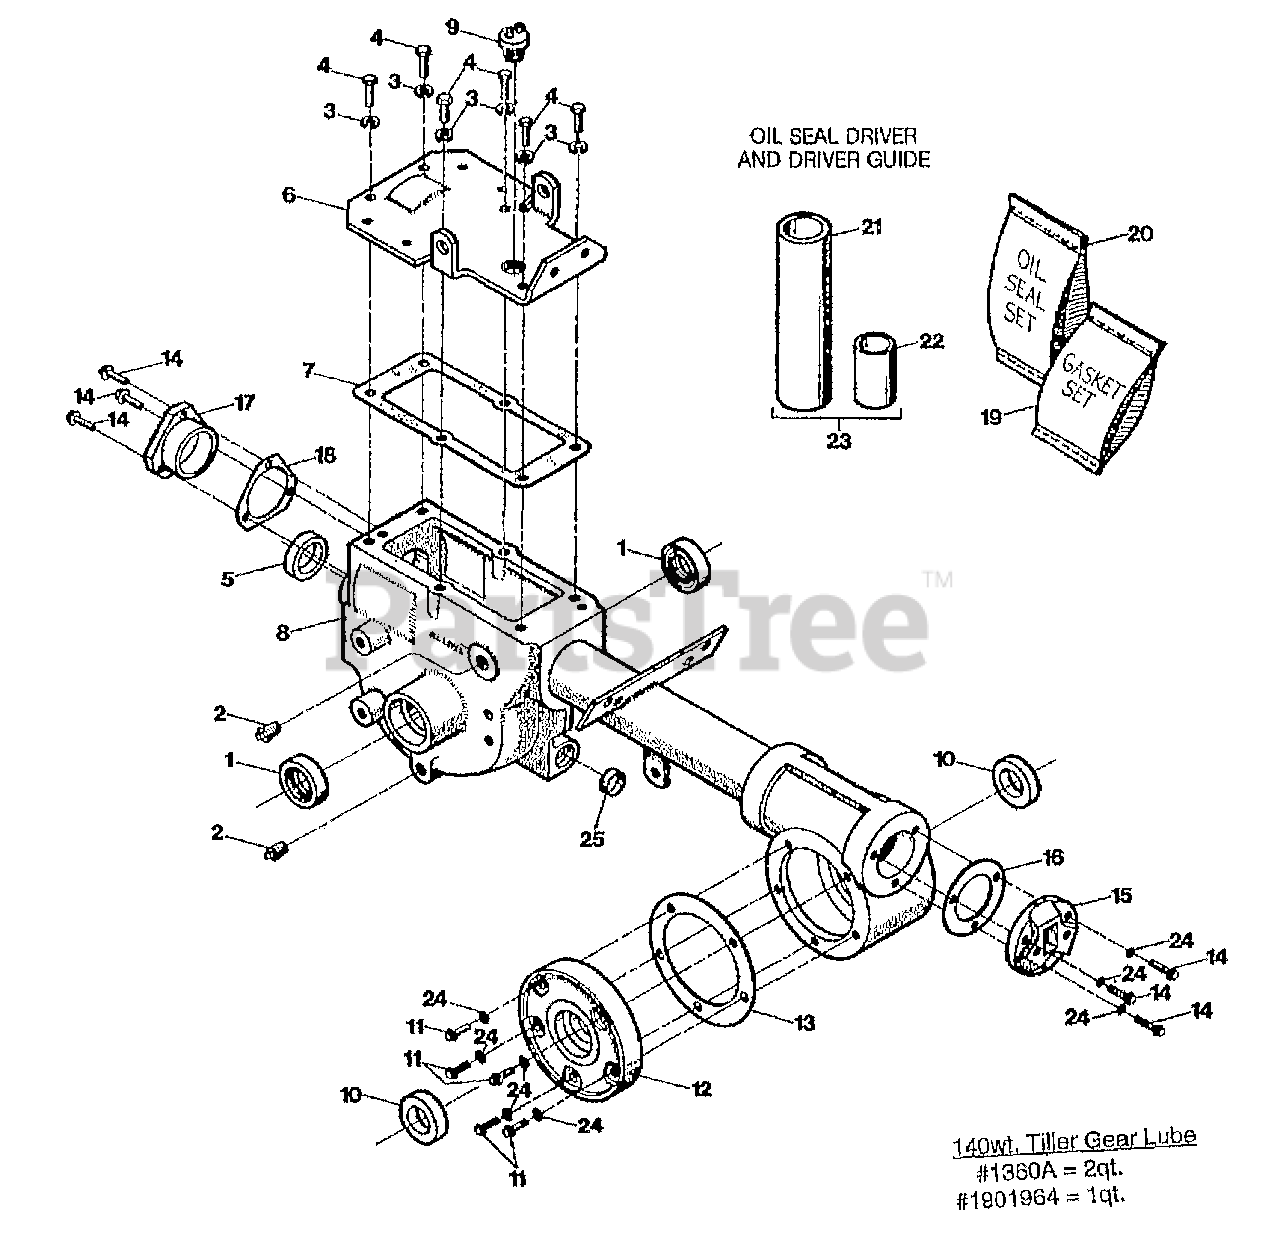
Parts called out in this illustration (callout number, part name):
1	SEAL-OIL WHEELSHAFT (Double lip, wheel shaft, RT & LT sides.)
2	PLUG-PIPE 1/4 NPT (Oillevel hole and gear oil drain hole.)
3	WASHER-LK .312 ZP (Transmission top cover)
4	SCR-HHC 5/16-18X.75 GR 5 ZP (Transmission top cover)
5	SEAL-PINION SHAFT PT/85030/00 (Input pinion shaft, front of transmission)
6	COVER-TRANS (Top of Transmission)
7	GASKET-TRANS COVER
8	HSG-TRANS P5 A UNIT (Inc. #9429 rear bearing race)
9	PLUG-OIL FILL 3/4-10 (For gear oil fill hole on transmission cover.)
10	SEAL-TILLER SHAFT (LT & RT sides.)
11	SCR-HH 1/4-20X.625
12	COVER-RTH W/SCRS & RACE
13	GASKET-TILLER COVER (Fits all covers)
14	SCR-HFLK 1/4-20X.875
15	CAP-REAR #1115
16	GASKET-BRG COVER
17	COVER-FRONT BEARING
18	GASKET-FRONT COVER-.010
19	GASKET SET-P4 (Inc. 1 #7, 1 #18, 2 # 13, 1 1129-2 .030", 2 #16)
20	OIL SEAL SET-PONY V (Inc. 2 #1, 2 #10, 1 #50)
21	DRIVER-PLASTIC (For wheel shaft & tiller shaft oil seals.)
22	SEAL-DRIVER PILOT (To install wheel shaft & tiller shaft oil seals.)
23	KIT-DRIVER (Inc. 21 & 22)
24	WASHER - Nylon, not reusable
25	PLUG-BORE (For bore hole directly beneath the front of the transmission tube.)
